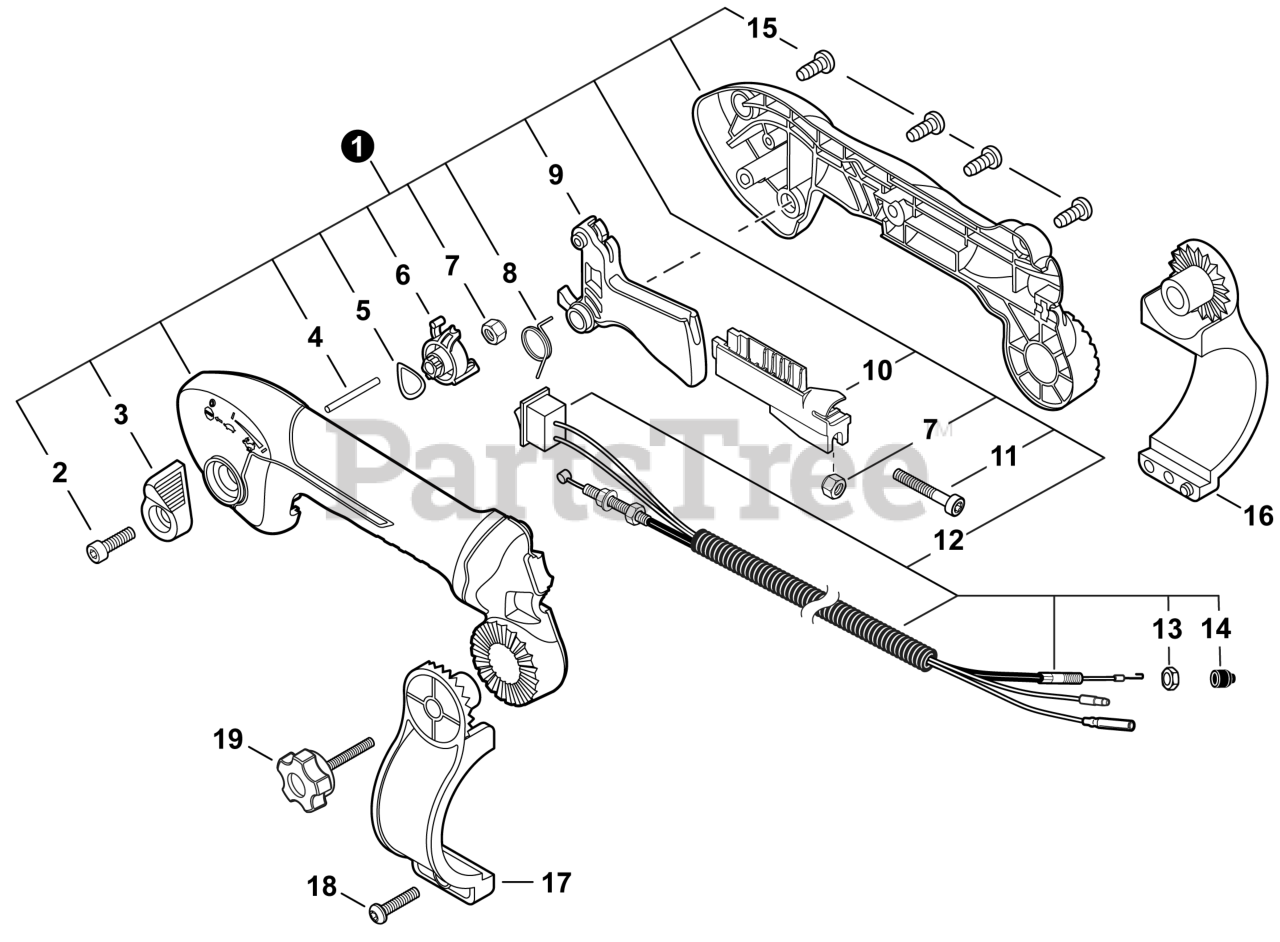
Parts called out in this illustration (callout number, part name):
1	THROTTLE CONTROL KIT - TUBE MOUNT
2	BOLT, TORX 5×20
3	LEVER, THROTTLE
4	PIN 3×32
5	WASHER, WAVE 12
6	CONTROL, THROTTLE
7	NUT, LOCK M5
8	SPRING, TORSION
9	TRIGGER, THROTTLE
10	CONNECTOR, CABLE
11	BOLT, TORX 5×30
12	CABLE ASSY, CONTROL
13	NUT, HEX M6
14	CAP, DUST
15	BOLT, TORX 5×16
16	BRACKET, HANDLE - RIGHT
17	BRACKET, HANDLE - LEFT
18	BOLT, TORX 5×20
19	KNOB, SCREW
